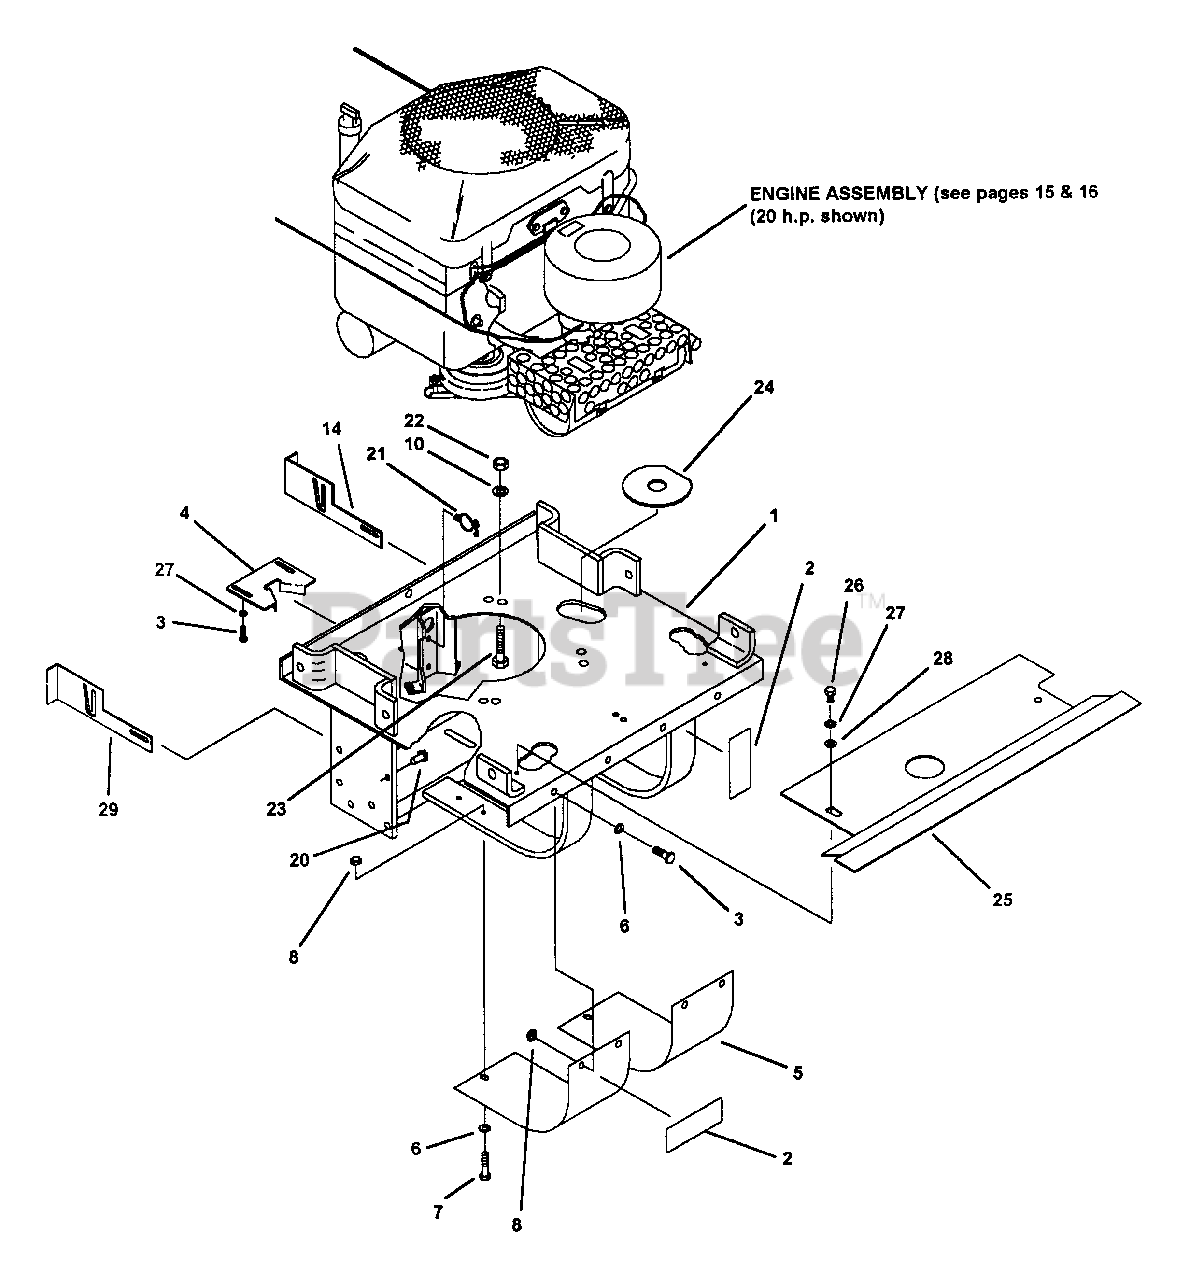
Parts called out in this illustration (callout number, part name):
1	MOTOR MOUNT WELDMENT
2	DECAL, FAN SHIELD
3	CAPSCREW, 1/4-20 X 3/4" GR. 5
4	CLUTCH STOP PLATE
5	FAN SHIELD
6	WASHER, FLAT, STD. 1/4"
7	CAPSCREW, 1/4-20 X 1" GR. 5
8	NUT, HEX HD. 1/4-20, NYLOC
10	LOCKWASHER, 5/16" SPLIT SPRING
14	FREEWHEEL BAR R.H.
20	DRIVE STUD, 1/4 X 1/2" LONG
21	BLINDHOLE KURLY-LOC
22	NUT, 5/16-18 UNC, GR. 5 PLATED
23	BOLT, 5/16-18 X 1-1/2" GR. 5
23	BOLT, M8 X 1.25 X 25 HEX HD.
24	WASHER, SEAL
25	REAR SHIELD
26	SCREW, 1/4 X 3/8" SELF THRD. FORM
27	LOCKWASHER, SPLT. SPRING 1/4"
28	WASHER, FLAT 1/4" ZINC PLATED
29	FREEWHEEL BAR L.H.
